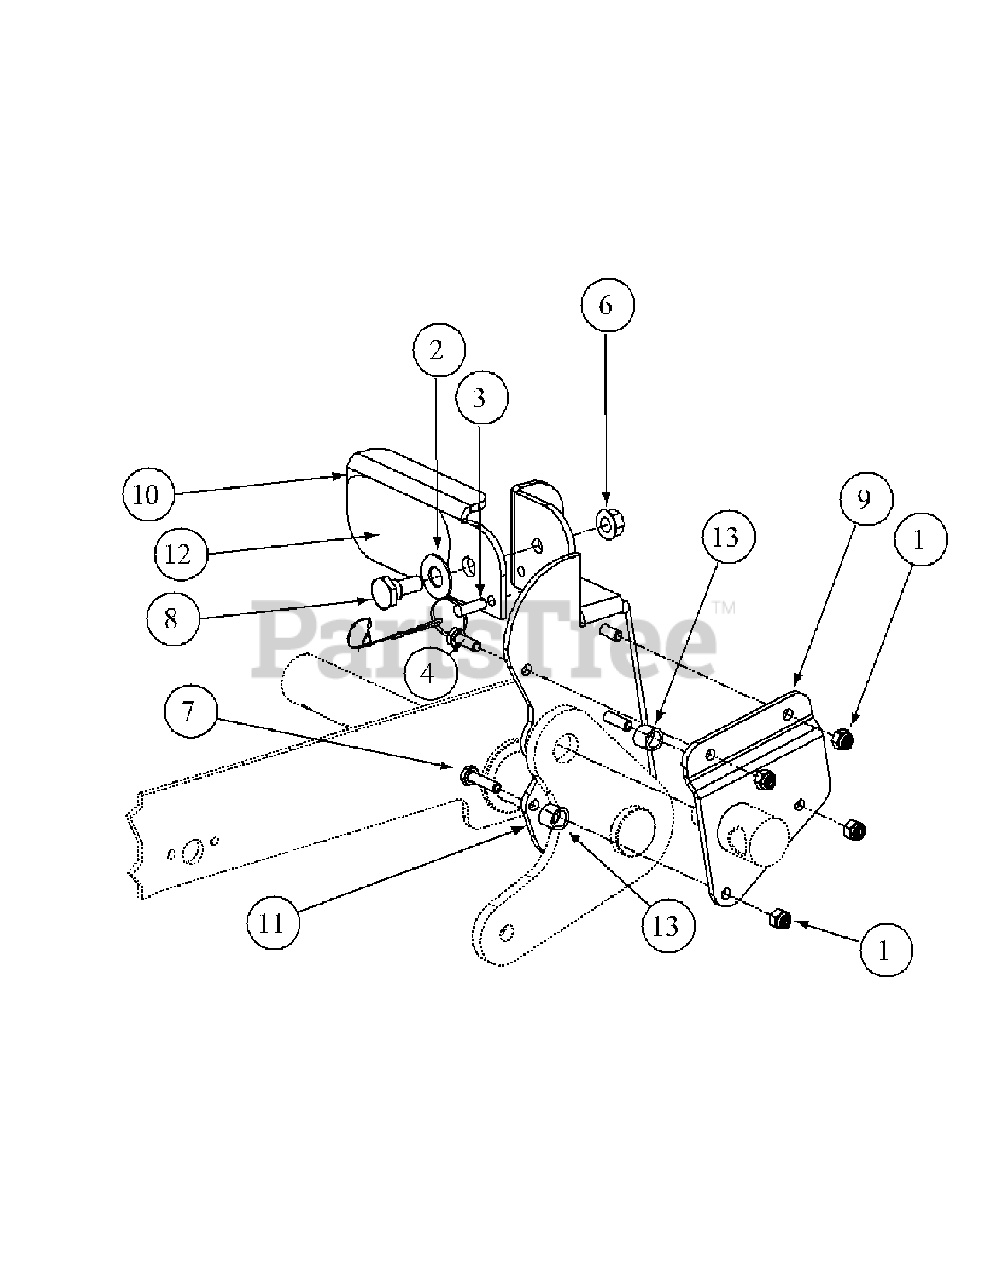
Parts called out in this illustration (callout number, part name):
1	Lock Nut, Nylon Insert, 1/4-20
2	Washer, 1/2 x 1 Shim
3	Detent Pin w/12" Lanyard
4	Hex Cap Screw, 1/4-20, .75
6	Hex Nut, Flange Lock 3/8-16
7	Hex Cap Screw, 1/4-20, 1.00
8	Shoulder Screw, .50 x .27 Lg., 3/8-16
9	Foot Lift Backup Pedal
10	Deck Foot Pedal Lift
11	Deck Foot Pedal Lift
12	Deck Foot Lift Pad
13	Turnbuckle Sleeve
